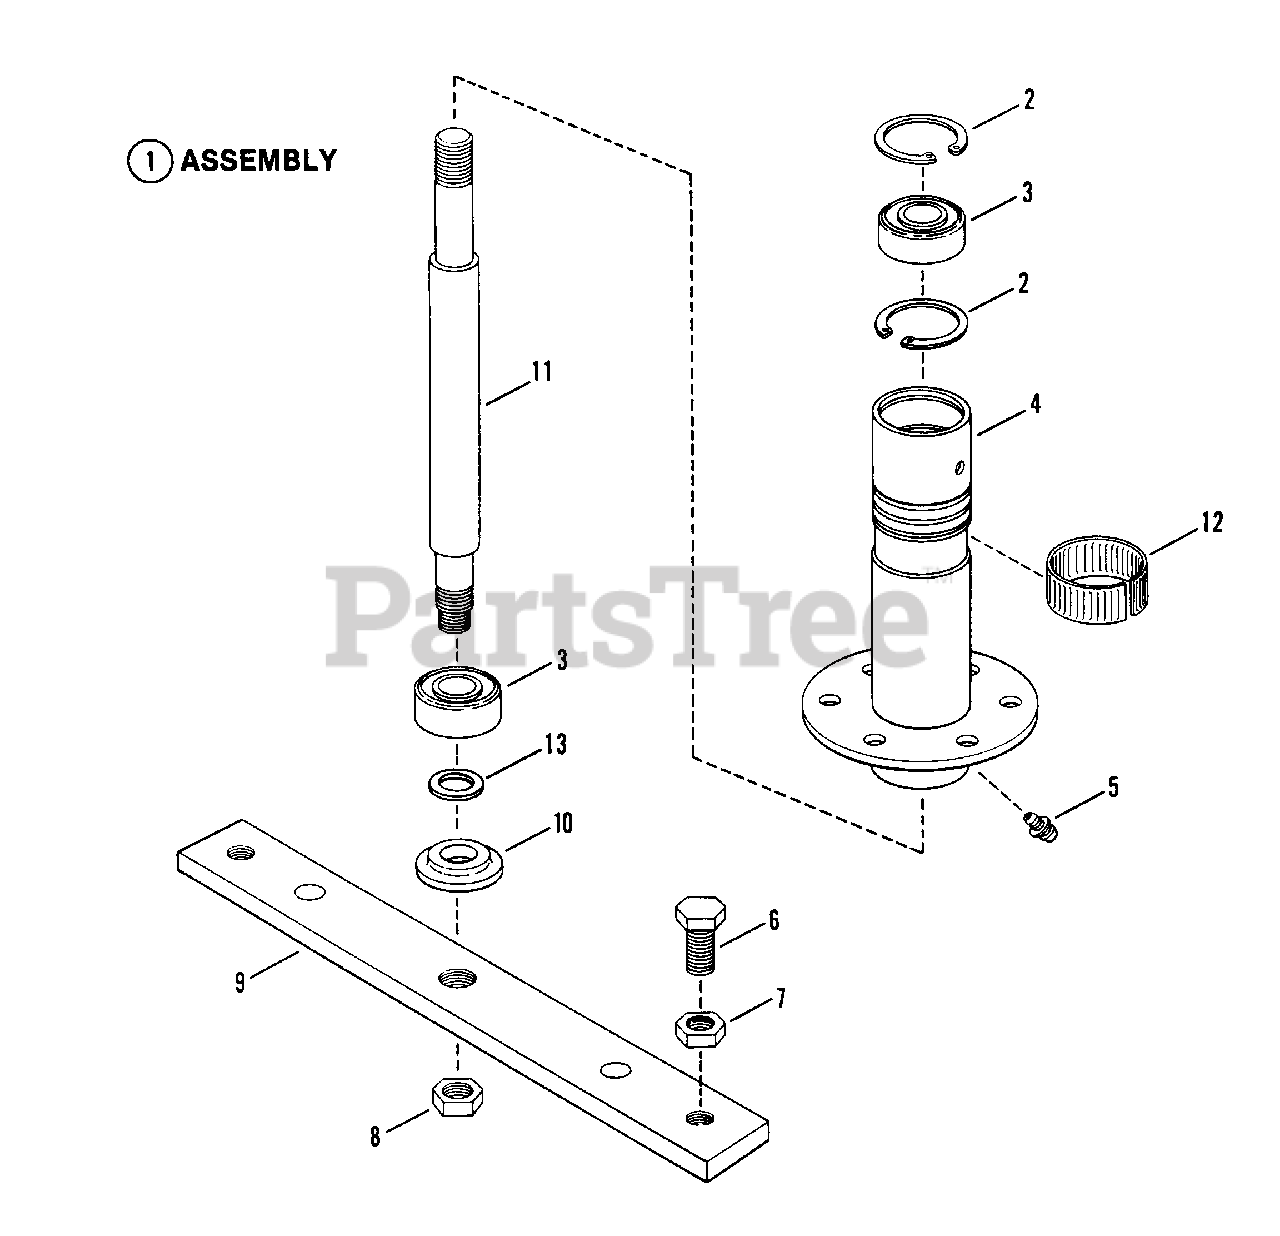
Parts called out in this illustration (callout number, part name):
1	ASSEMBLY, Spindle Housing
2	RING, Retaining
3	BEARING, Spindle
4	HOUSING, Spindle
5	FITTING, Lube (Press fit for .187 hole-no ball)
6	SCREW, 1/2-20 x 1" Hex Head Cap (GR.5)
7	NUT, 1/2-20 Hex Jam
8	NUT, 5/8-18 Hex Lock
9	HOLDER, Blade
10	WASHER, Spindle
11	SPINDLE, Shaft (10.237" Long)
12	RING, Tolerance
13	WASHER, Shim
